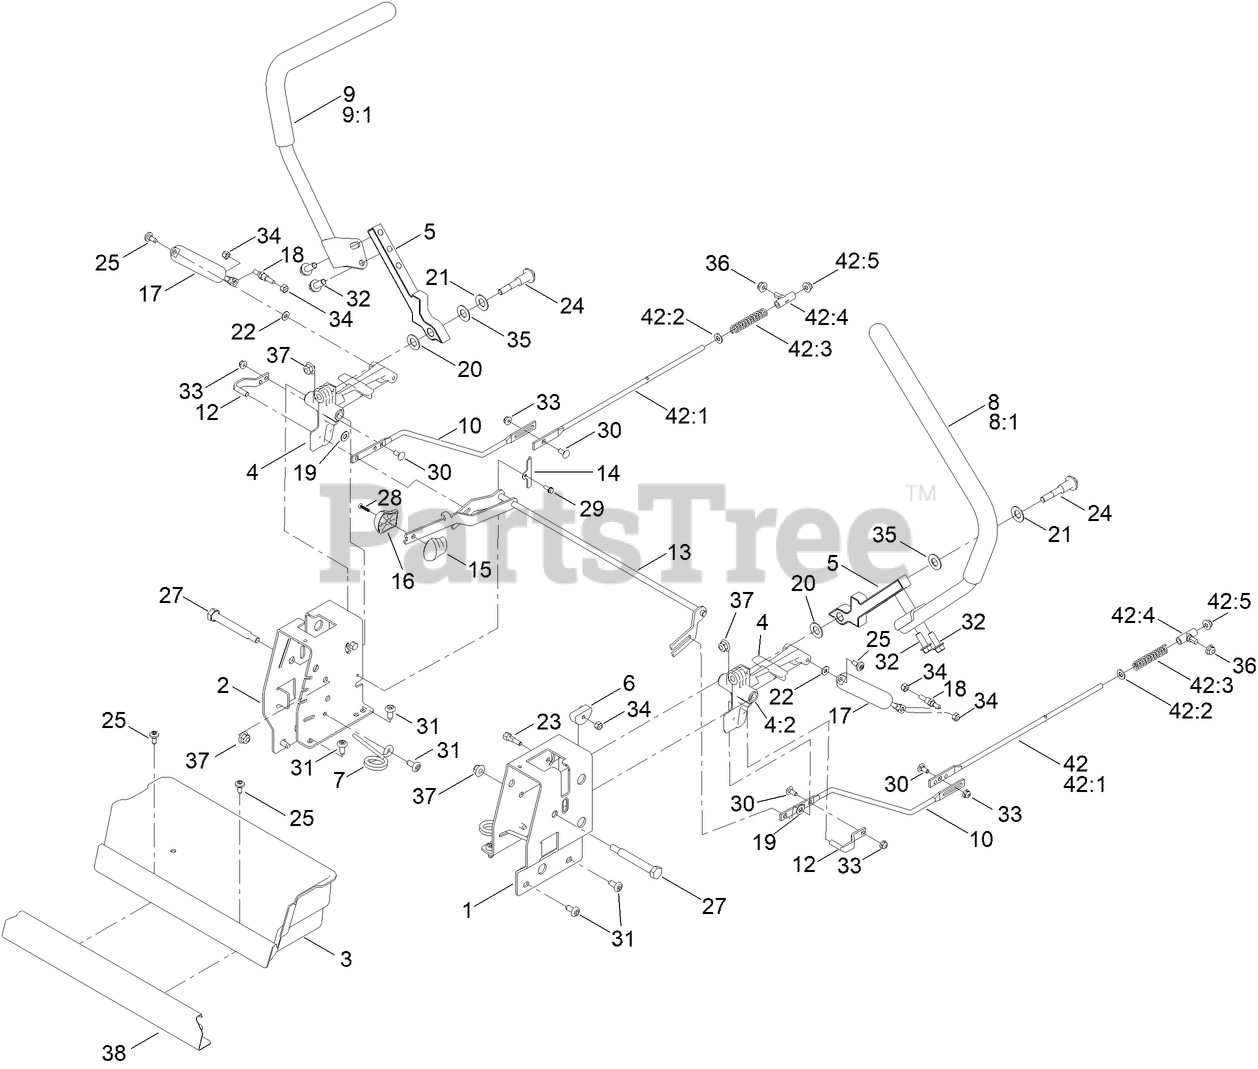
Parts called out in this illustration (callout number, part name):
1	PLATE-CONTROL BOX, LH
2	PLATE-CONTROL BOX, RH
3	BOX-STORAGE
4	ACTUATOR ARM ASM
4:2	BUSHING-FLANGE
5	ARM-CONTROL
6	ECCENTRIC
7	SPRING-TORSION
8	HANDLE-CONTROL, LH
9	HANDLE-CONTROL, RH
10	ROD-HYDRO, FRONT
12	PIN-ROD, HYDRO
13	SPEED CONTROL ASM
14	PLATE-RETAINER
15	KNOB-RH
16	KNOB-LH
17	DAMPER-NON CAVITATING
18	STUD-DAMPER
19	SPACER-NYLON
20	WASHER-NYLON
21	WASHER-BELLEVILLE
22	WASHER
23	BOLT-PIVOT, ECCENTRIC
24	BOLT-PIVOT
25	SCREW-SHOULDER
27	BOLT-PIVOT
28	SCREW-PPH
29	SCREW-TAPTITE
30	SCREW-CARR
32	SCREW-HHF
33	NUT-HF
34	NUT-LOCK, NI
35	WASHER
36	NUT-HF
37	NUT-HF, NI
38	PLATE-KICK
42	ROD HYDRO ASM
42:1	ROD-HYDRO, REAR
42:2	WASHER-PLAIN
42:3	SPRING-COMPRESSION
42:4	MOUNT-ROD, HYDRO
42:5	NUT-HF
